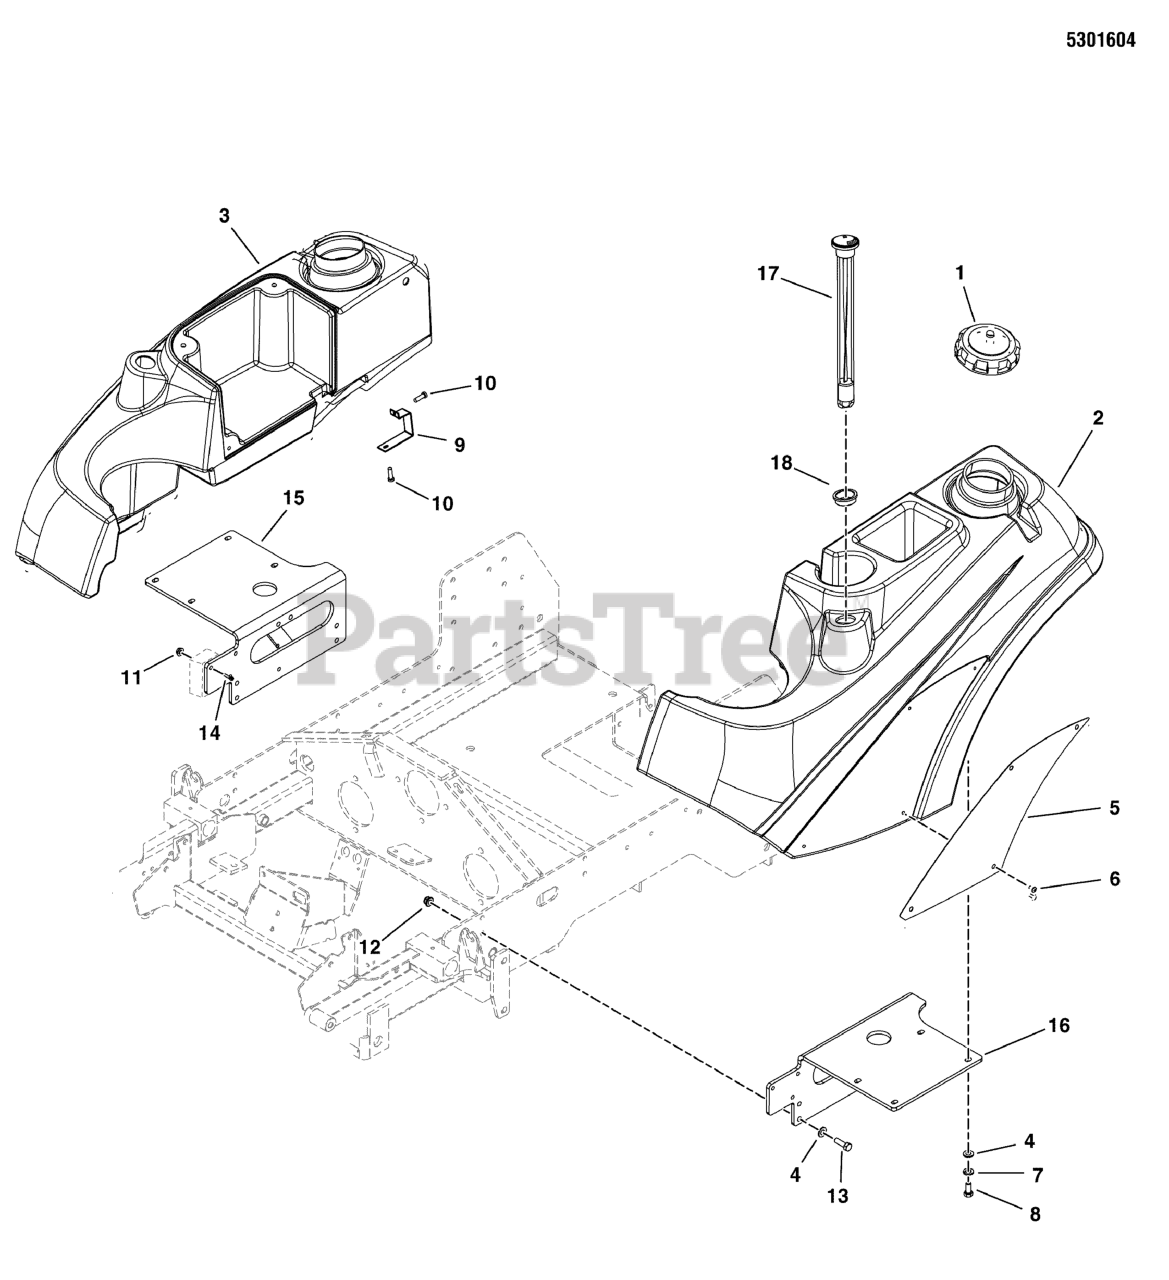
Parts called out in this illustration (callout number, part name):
1	FUEL CAP, 3.5", NON VENTED, DIESEL (GRN)
2	TANK, FUEL, LH, IS2500Z
3	TANK, FUEL, RH, IS2500Z
4	WASHER, 5/16" SAE
5	BADGE, IS2000 - IS3000 - RED
6	SCREW, #10-24 X 3/8 ALLEN BHBZ
7	WASHER, 5/16 LOCK CZ
8	BOLT, 5/16-18 X 3/4 GD5
9	GUARD, FUEL TANK - RED
10	SCREW, 1/4-20 X 1/2 ALLEN BH
11	NUT, #10-24 HEX
12	NUT, 5/16-18 HEX NYLOCK FLANGE
13	BOLT, 5/16-18 X 1 GD5 YZ
14	SCREW, #10-24 X 3/4 ROUND PHILLIPS
15	WELD, MOUNT, TANK, RH - BLK
16	WELD, MOUNT, TANK, LH - BLK
17	GAUGE, FUEL, 12
18	GROMMET, FUEL GAUGE (SV)
